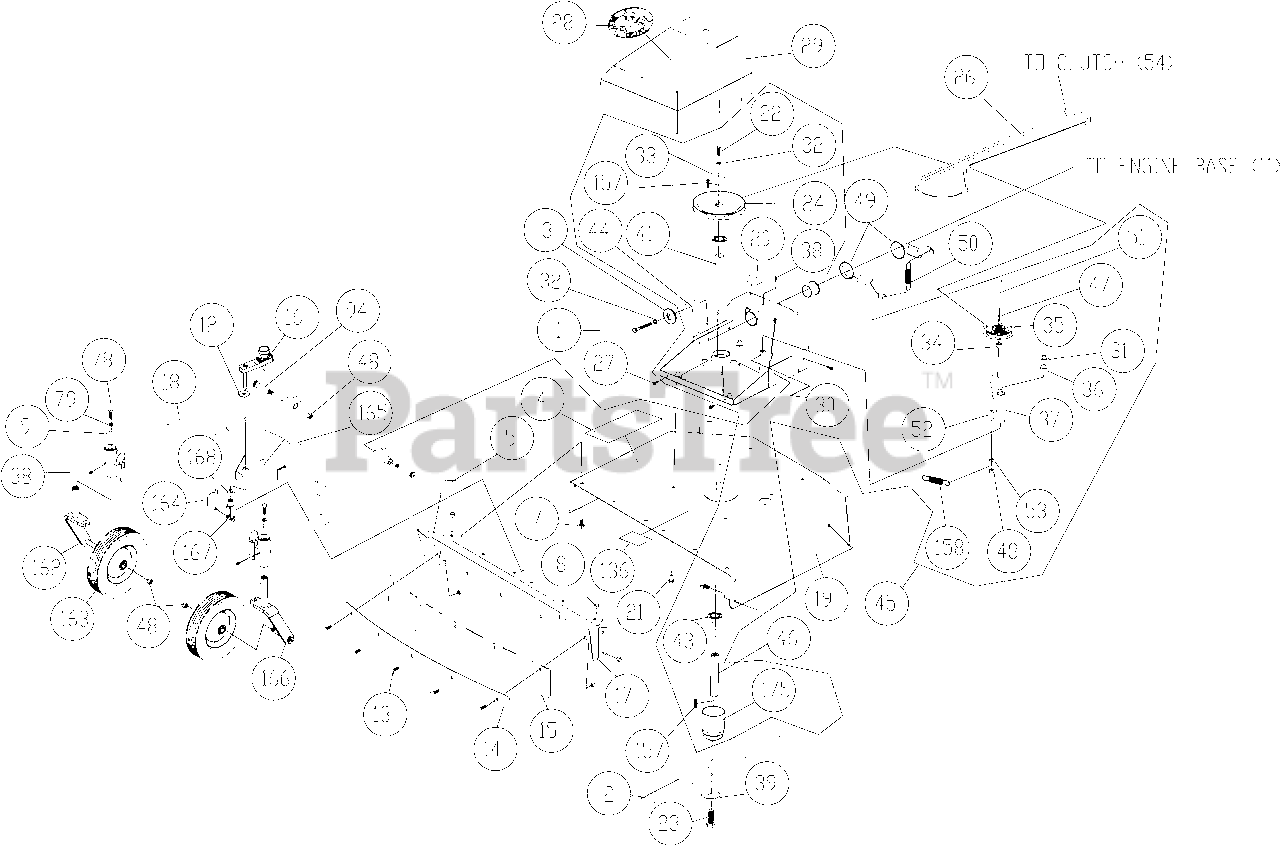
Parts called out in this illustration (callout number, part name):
1	SCREWCAP 3/8-24 X 1” HCS GR. 8
2	BLADE 26” FLAT BC26
3	WASHER DECK RETAINNG
4	LABEL BADGING BC26 HYDRO
5	LABEL DANGER
7	BOLT CARRIAGE 5/16”-18 X 3/4” ZP
8	NUT LOCK 5/16-18 ZP
9	WASHER 1.125” OD X 0.344” ID X .25” THK
12	BUSHING FLANGED 1.250” X 0.380” ID
13	CARRIAGE BOLT 5/16”-18 X 1”
14	PLATE FRONT DEFLECTOR
15	RUBBER DEFLECTOR FRONT
16	HEIGHT ADJUST HANDLE ASSY
17	DECK INTAKE WA EURO BC26
18	CASTER FRAME WA
19	DECK BC26EU WA W/LABELS
20	LABEL DANGER GUARD
21	SCREW SER HEX WASHER FLNG
22	SCREWCAP 3/8”-16 X 1 1/4” HCS ZP
23	SCREWCAP 9/16”-18 X 1 3/4” GR 8
24	PULLEY 7” OD X 1.000 BORE
26	BELT 6972 POWERATED
27	SCREW SELT TAP 1/4-20 X 5/8” HWH TYPE F
28	LABEL PRODUCT DECAL LG CIRCLE
29	COVER BELT DECK WA BC26 W/LABEL
30	PIN COTTER 1/8” X 1”
31	WASHER .765 ID X 1.25 OD X .06 THK
32	WASHER LOCK 3/8 S/T MED
33	WASHER 1.5 OD X .453 ID X .25 THK
34	TUBE PIVOT IDLER VQ
35	PULLEY IDLER 4.00 OD X 3/8” BORE
36	BUSHING PIVOT FRAME AE
37	ARM IDLER DECK WA BC
38	ZERK FITTING GREASE
39	WASHER BLADE BC26
41	SPACER SPINDLE BEARING BC26
43	BEARING 1.00” SEALED PRESS IN
44	BUSHING 1.500 ID X 1.5 LONG FLANGED
45	BRACKET DECK MOUNT WA BC26 W/LABEL
46	SHAFT BLADE BC26
47	WASHER 3/8” SAE
48	NUT LOCK 3/8-16 HEX
49	ARM RTN WA BC26
50	SPRING LIFT ASSIST TENSION
51	SCREWCAP 3/8”-16 X 3 3/4” HCS ZP
52	BUSHING PIVOT LIFT
53	NUT LOCK 3/8”-16 LT WT TH ZP
78	SCREWCAP 5/16”-18 X 1” GR 5 HCS ZP
79	WASHER LOCK 5/16” S/T MED
94	BOLT SHOULDER 1/2” X 2”
136	LABEL WARNING FLYING DEBRIS
157	KEY 1/4 SQ. X 0.75”
158	SPRING IDLER BC
162	CASTER RIGHT SIDE WA
163	TIRE WHEEL ASSY
164	SPRING PIN CLEVIS
165	LABEL HEIGHT ADJUST EURO BC26
166	CASTER LEFT SIDE WA
167	YOKE FEMALE STEEL 3/8”-24 RH X 2.50
168	NUT LOCK 3/8”-24 ZP THIN HT
175	ADAPTER BLADE WA BC26
